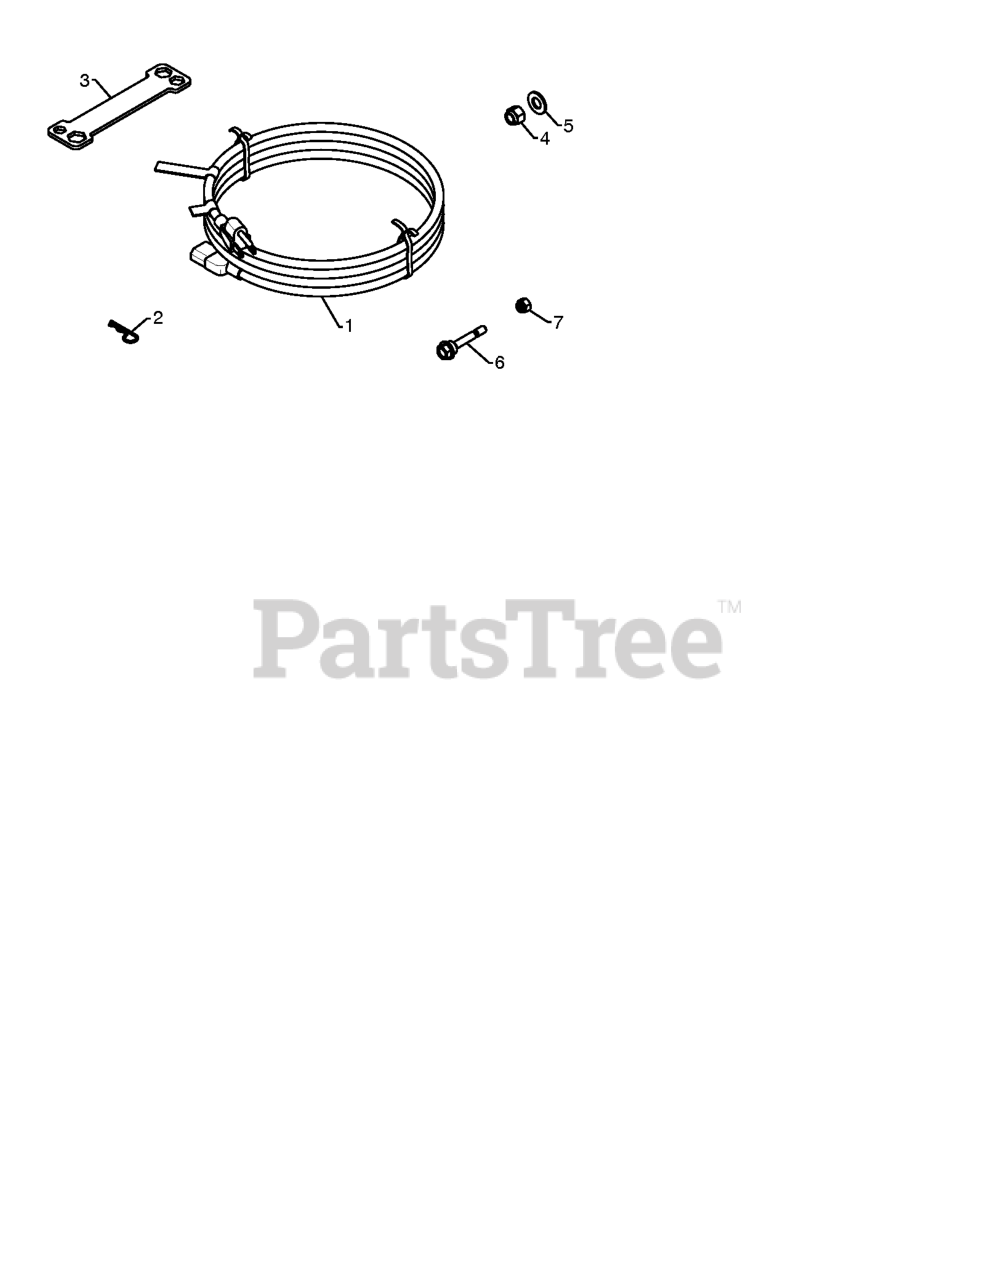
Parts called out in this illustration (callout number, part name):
1	CORD.ELECTRIC.10FT.120V.SNOW
2	SPRING RETAINER
3	WRENCH.SNOWTHROWER.ZINC.YZ
4	NUT
5	WASHER
6	BOLT.SHOULDER.SHEAR.1/4-20.
7	LOCKNUT.NYLOC.1/4-20
